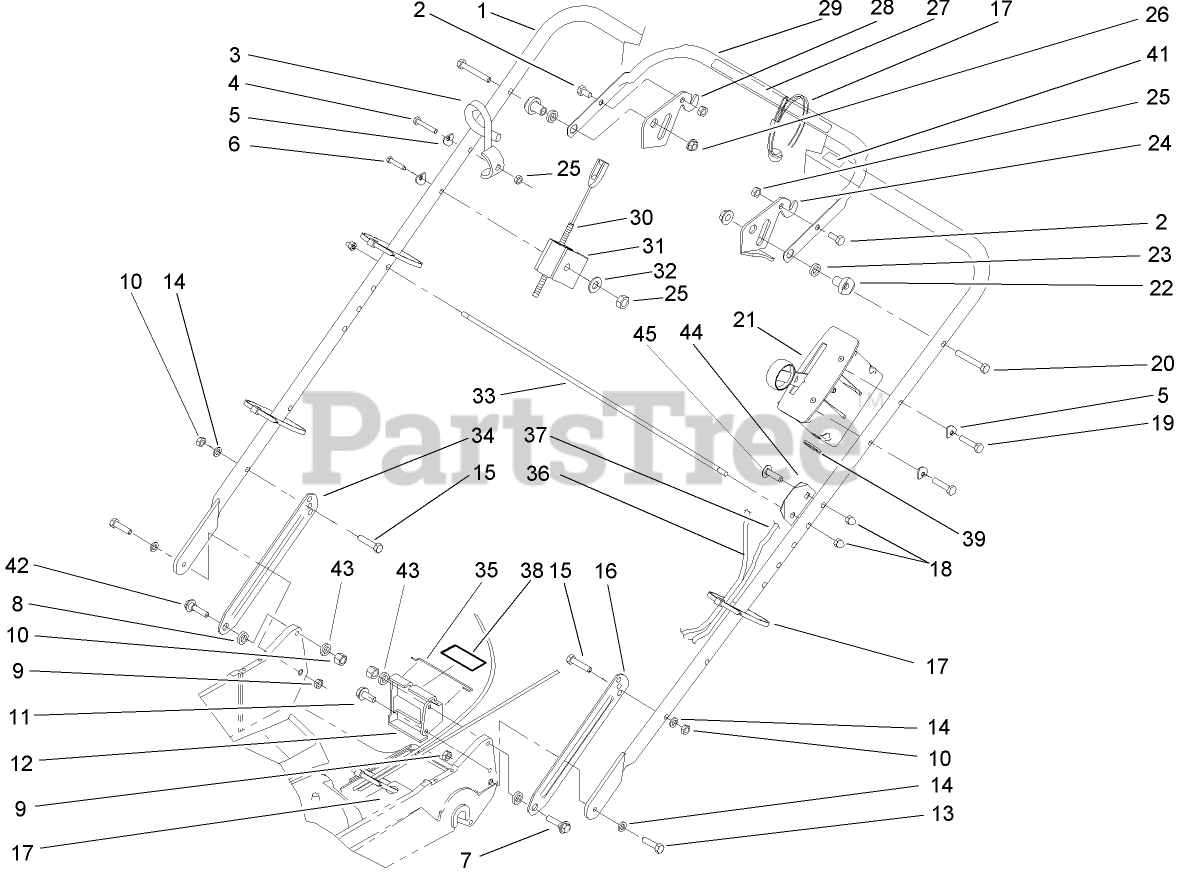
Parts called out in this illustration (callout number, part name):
2	SCREW-HH
3	GUIDE-ROPE
4	SCREW-HH
5	WASHER
6	SCREW-HH
7	SCREW-SHOULDER
8	SPACER
9	NUT-LOCK, NI
10	NUT-LOCK, NI
11	SCREW-HWHTF
12	BRACKET-ADJUSTMENT, TRACTION
13	SCREW-HH
14	WASHER-BELLEVILLE
15	SCREW-HH
16	LATCH-HANDLE, LH
17	TIE-CABLE
18	NUT-CAP
19	SCREW-HH
20	SCREW-HH
21	CONTROL-HEAD, THROTTLE
22	SPACER-SUPPORT
23	SPACER-NYLON
24	LEVER-CONTROL
25	NUT-LOCK, NI
26	NUT-LOCK, NI
27	DECAL-TRACTION
28	LEVER-CONTROL
29	BAR-CONTROL
30	CABLE-BRAKE
31	SUPPORT-CABLE
32	WASHER-FLAT
33	ROD-SUPPORT, BAG
34	LATCH-HANDLE, RH
35	RETAINER-CABLE
36	CABLE-TRACTION
37	THROTTLE CABLE ASM
38	DECAL-POSITION, GEAR
39	E-RING
41	DECAL-PROTECTION, EAR
42	SCREW-SHOULDER
43	WASHER-PLAIN
44	PLATE-ALIGNING, BAG
45	SCREW-CARR
